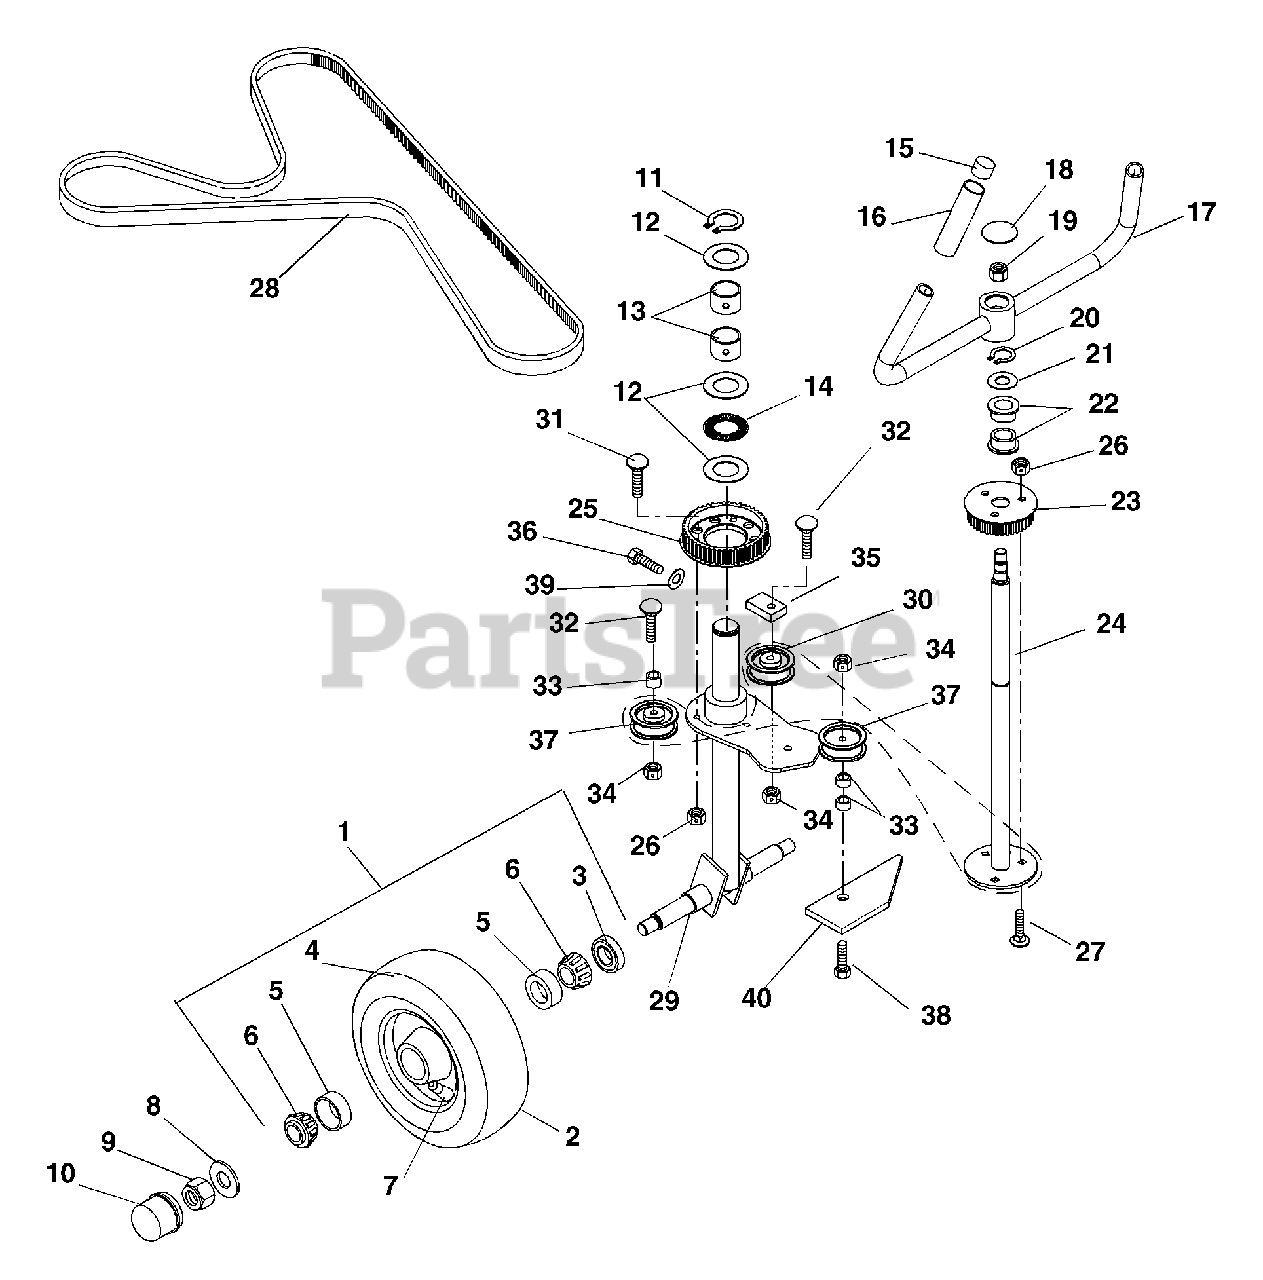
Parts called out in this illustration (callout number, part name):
1	Tire/Wheel Assembly 6.50-8
2	Tire, 16 x 6.5-8 4-Pulley Rib Tread
3	Seal
4	Wheel Assembly 3.75 x 8
5	Bearing-Cup 1.980 x 4.20
6	Bearing-Cone 1.0 x .58
7	Valve Stem Assembly
8	Washer, Flat-Steel .812 x 1.50 x .135
9	Nut, Locking-Center .75-10
10	Cap, Dust
11	Ring, Retaining-External 1.50 x 1.38
12	Washer-Thrust 1.502 x 2.18 x .063
13	Bearing-1.00 x 1.13 x 1.00
14	Bearing-Needle-Thrust 1.50 x 2.18 x .078
15	Caplug, Handlebar
17	Weldment, Handlebar
18	Hole Plug 1.38
19	Nut-Locking-Nylon .625-18
20	Ring-Retaining-External .906 x .078
21	Washer-Thrust 1.55 x 1.00 x .09
22	Bushing-Flange 1.02 x 1.38 x .75 x 1.75
23	Sprocket, Steering
24	Weldment, Steering Shaft
25	Sprocket, Drive
26	Nut-Locking-Center .31-18
27	Bolt-Round Head Square Neck .31-18 x 1.50 Grade 5
28	Belt, Double COG
29	Weldment, Caster Wheel
30	Idler- 2.25 x .87
31	Bolt-Round Head Square Neck .31-18 x 1.00 Grade 5
32	Bolt-Round Head Square Neck .38-16 x 2.00 Grade 2
33	Spacer .38 x .75 x .236
34	Nut-Locking-Nylon .38-16
35	Plate, Idler Adjustment
36	Bolt-Hex .31-24 x 1.50 Grade 5
37	Idler-Flat 2.75 x .38
38	Bolt-Hex .38-16 x 2.25 Grade 5
39	Washer-Flat-Steel .344 x .688 x .065
40	Washer, Fender Stiffener
